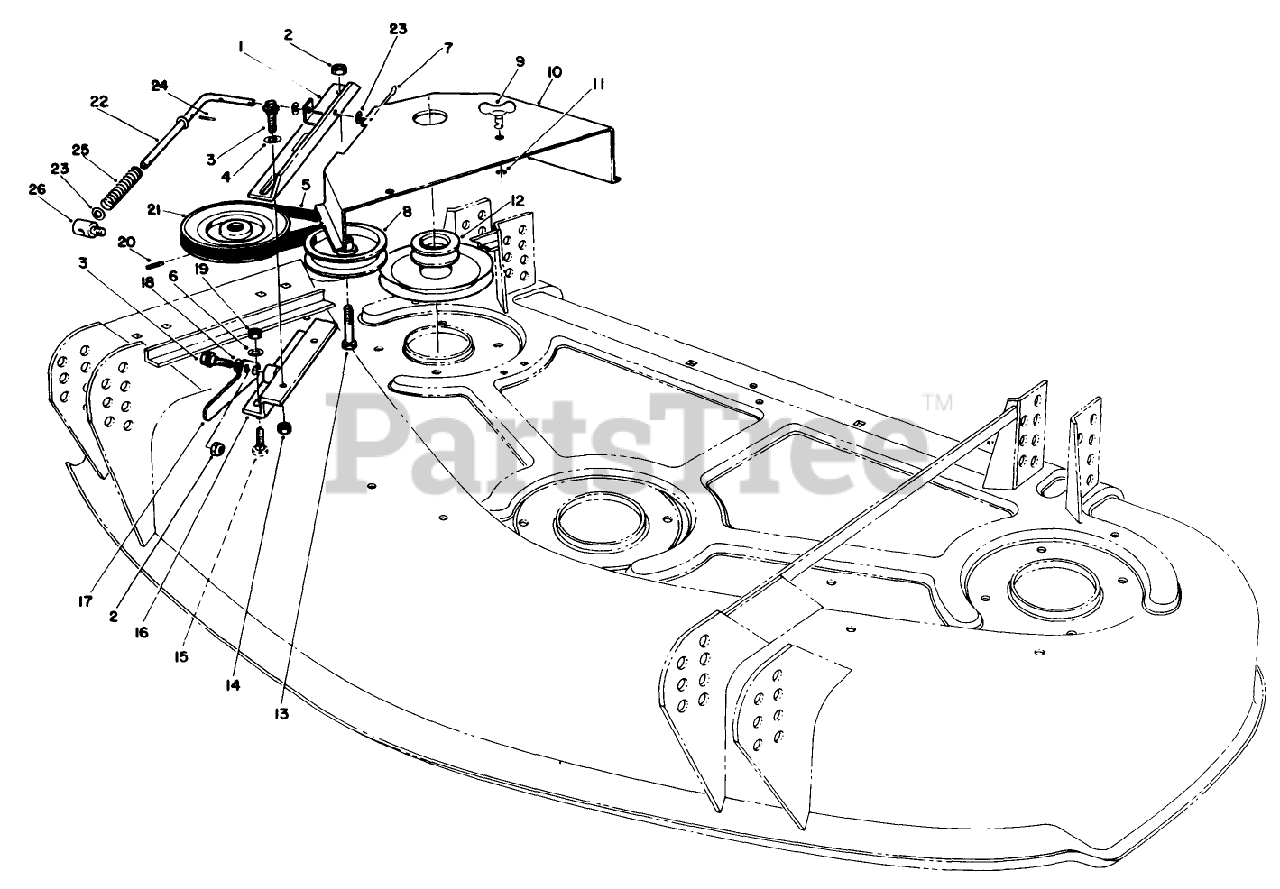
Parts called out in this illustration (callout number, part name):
1	Slide ldler
2	NUT-LOCK, NI
3	SCREW-SHOULDER
4	WASHER-THRUST
5	V-BELT
6	WASHER-PLAIN
7	PIN-COTTER
8	PULLEY-IDLER
9	STUD-HEAD, WING
10	Cover-Deck
11	RING-SNAP
12	DECK PULLEY WA
12	PULLEY
13	SCREW-HH
14	NUT-LOCK, NI
15	SCREW-CARR
16	Bracket-Idler
17	Lever-Idler
18	WASHER-SPRING
19	NUT-KEPS
20	PIN-ROLL, SLOTTED
21	Pulley-Gear Box
22	Rod-Idler
23	WASHER-FLAT
24	PIN-ROLL
25	COMPRESSION SPRING
26	BAGGER TRUNNION
